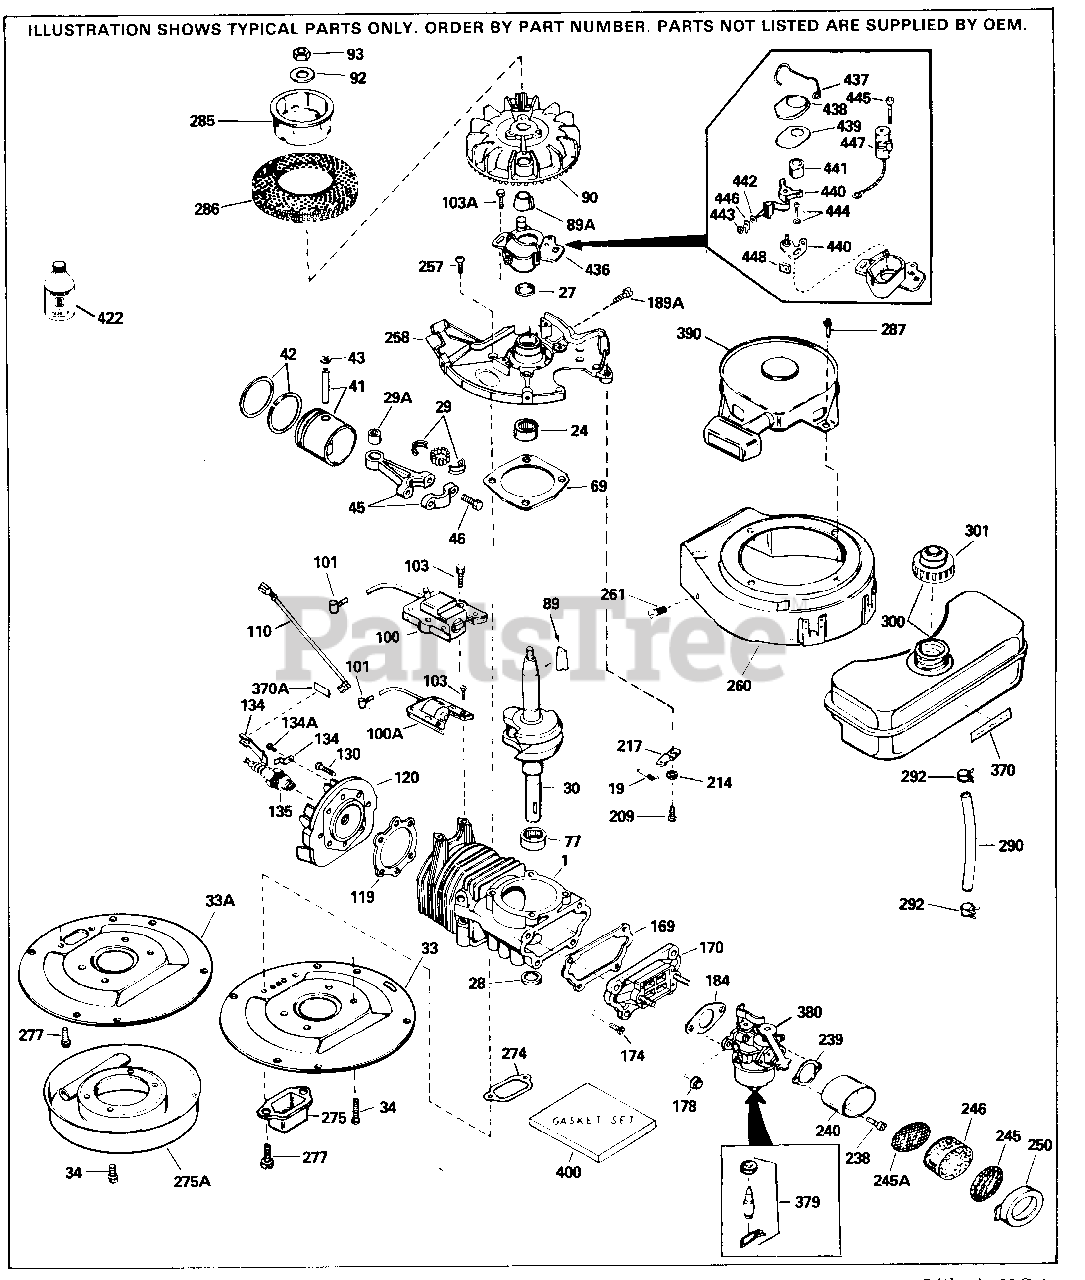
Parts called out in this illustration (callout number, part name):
1	"Cylinder Order s/b if replacement is req.
19	Spring, Governor
24	Bearing, Cartridge
27	Seal, Crankshaft
28	Oil Seal
29	Bearing & Liner Set, Needle 37 needl es
29A	Bearing, Cartridge
30	Crankshaft
33A	Ring, Adapter (8" B.C.)
34	Screw, 5/16-18 x 1/2"
41	Piston & Pin Ass'y. (Incl. 43)
42	Ring Set, Piston
43	Ring, Piston pin retaining
45	Rod Assy., Connecting Incl. 29,29A,4 6
46	Screw, Connecting rod
69	* Gasket, Housing base
77	Bearing, Cartridge
89A	Sleeve, Keyed adapter (Solid State)
90	Flywheel
92	Washer, Belleville
93	Nut, Hex Jam
100	Solid State Assy.
101	Terminal, Lead wire
103	Screw, 10-24 x 1"
119	* Gasket, Cylinder head
120	Cylinder Head
130	Screw, Torx T-30, 1/4-20 x 3/4"
134	Stop Lever Assy.
134A	Screw, 1/4-20 x 1/2"
135	Resistor Spark Plug - RJ17LM
169	* Gasket, Reed plate
170	Plate Assy., Reed (Incl. 178)
174	Screw, Torx T-25, 10-24 x 1/2"
178	Nut, lock, 1/4-20
184	* Gasket, Carburetor
209	Screw, 10-24 x 1/2"
214	Washer, Flat No. 10
217	Lever, Adjustment
238	Screw, Torx T-25, 10-32 x 5/8"
239	* Gasket, Air cleaner
240	Body, Air cleaner
245	Air Filter
245A	Air Filter
246	Air Filter
250	Cover, Air cleaner
257	Screw, 1/4-20 x 5/8"
258	Base Assy., Housing (Incl. 24 & 27)
260	Blower Housing
261	Screw, 1/4-20 x 7/16"
274	* Gasket, Exhaust
275A	Muffler
285	Cup, Starter
286	Screen, Starter cup
287	Rivet (Can be purchased locally)
290	Fuel Line (8.62")
292	Fuel Line Clamp
300	Fuel Tank (Incl. 301)
301	Fuel Cap
370	Decal, Instruction
370A	Decal, Stop
379	Inlet Needle, Seat & Clip Assy.
380	Carburetor (Incl. 184) (Refer to Divi sion 5, Section A, page A1-26 or Fich e 23B, Grid F-9 for breakdown
390	Rewind Starter Refer to Division 5, S ection C, page 25 or Fiche 23B, Grid G-11for breakdown
400	* Gasket Set (Incl. items marked *)
422	2-Cycle Oil with Fuel Stabilizer - 8 oz.
